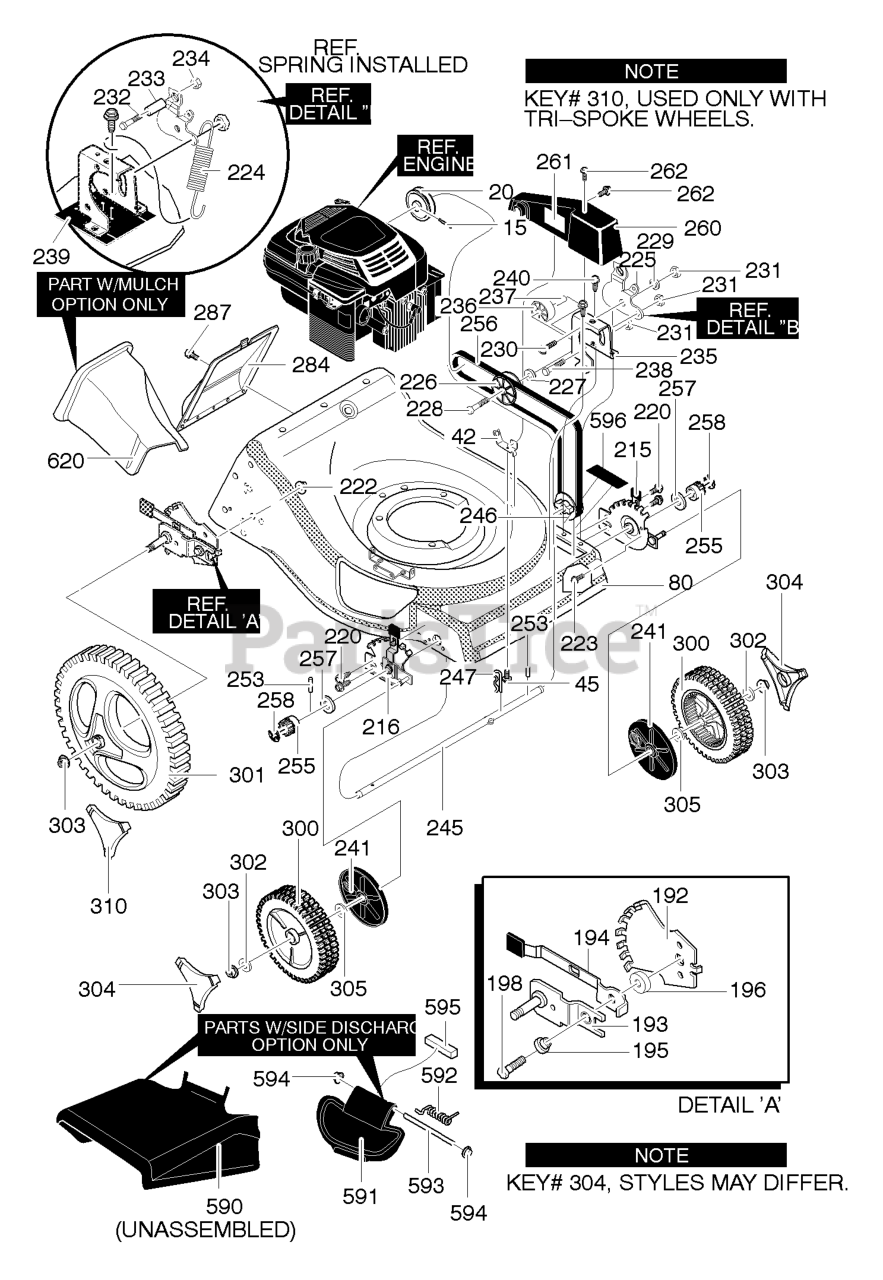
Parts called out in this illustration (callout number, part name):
15	PIN, SPRING
20	ENGINE PULLEY
42	BKT, DRIVE CABLE
45	SCREW, #8-32X.38
80	ASSY, FRAME
185	INDEX PLATE
193	AXLE & BRACKET
194	LEVER, SPRING
195	WASHER, FLAT .375X
196	SPACER, PLASTIC
198	SCREW, 3/8-16 x 1.50
215	ASSY, LF HGT ADJ
216	ASSY, RH HGT ADJ
220	SCREW, 1/4-20X.63
222	NUT, 3/8-16
223	SCREW, 10-24X.38
224	EXTENSION SPRING
225	IDLER ARM
226	IDLER PULLEY
227	SPACER, IDLER
228	BOLT, SH 5/16-18
229	SPACER, IDLER ARM
230	BOLT, CARR
231	NUT, 5/16-18
232	BOLT, SHOULDER
233	PULLEY, ROLLER
234	NUT, 5/16-18
235	BKT, IDLER SUPPT
236	PULLEY, IDLER
237	BEARING, SLEEVE
238	SCREW, 5/16-18
240	SCREW, 1/4-20X.50
241	DUST COVER
245	SHAFT, F/DR AXLE
246	PULLEY, F/DR AXLE
247	HAIR PIN
253	PIN, DRIVE
255	PINION GEAR
256	BELT, V3L
257	FLATWASHER
258	RING, RET E.
260	BELT COVER
261	HEAT SHIELD
262	SCREW, 10-24X.38
284	REAR COVER
300	WHEEL, DRIVE
301	TIRE & RIM
302	WASHER, FLAT
304	HUB CAP
305	FLAT WASHER
310	HUB CAP
590	DEFLECTOR, CHUTE
591	COVER, MULCH
592	SPRING, TORSION
593	ROD, PIVOT
594	CAP, PUSH ON
595	SEAL, FOAM
596	FLAP, BELT SCRAPER
620	PLUG, MULCHER
